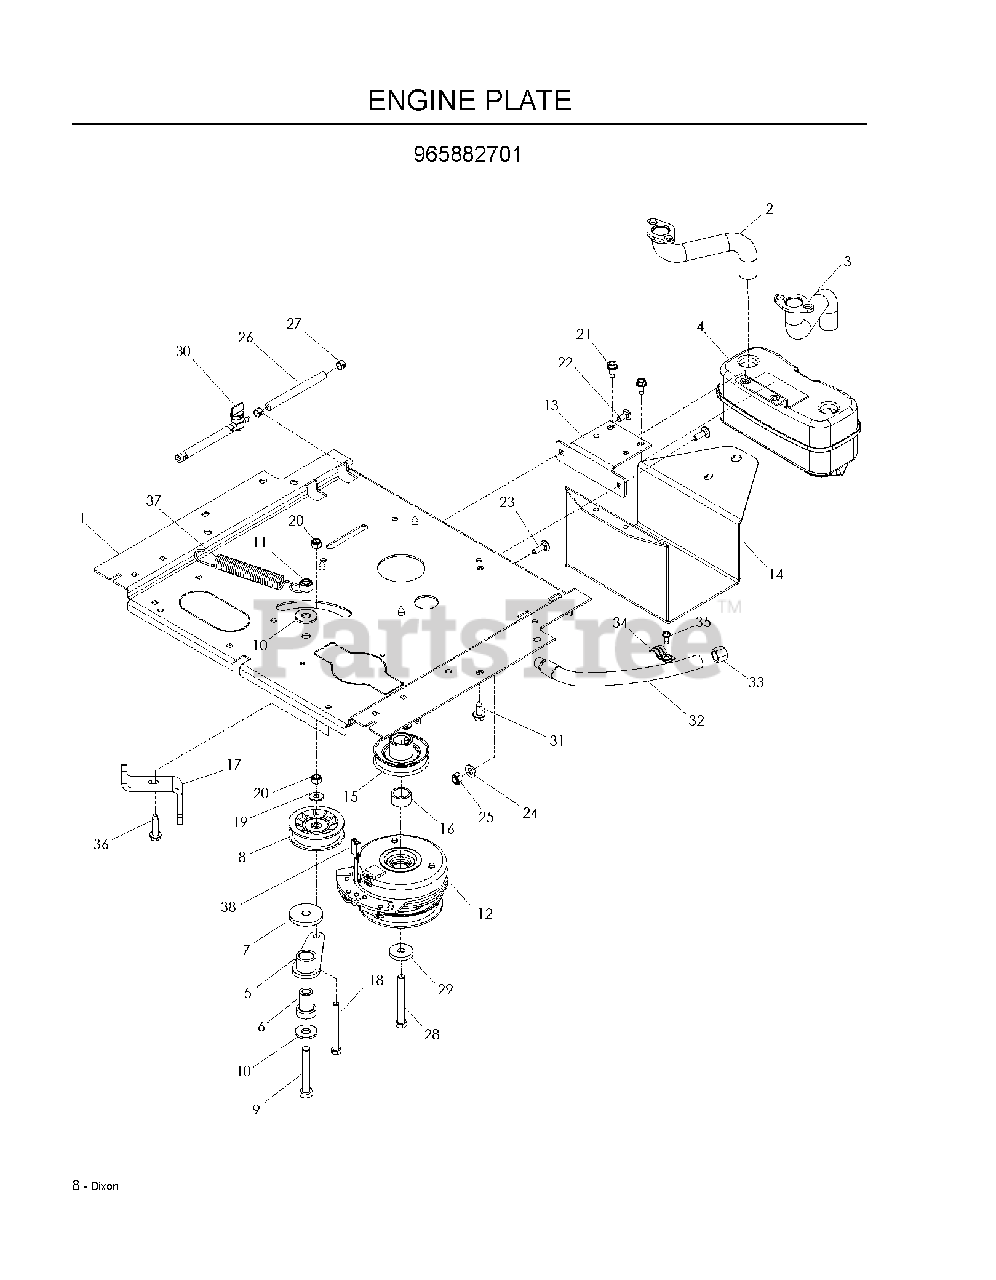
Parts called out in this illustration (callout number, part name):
1	PLATE, ENGINE, BLACK
2	RP.EXHAUST.TUBE.LH.BS/TWIN
3	RP.EXHAUST.TUBE.RH.BS/TWIN
4	MUFFLER ASM TWIN
5	IDLER SPINDLE
6	HEAVY WASHER
7	IDLER ARM WELDMENT
8	PULLEY, IDLER
9	HCS 1/2C X 3 1/4
10	WASH USS FLAT 1/2
11	NUT 1/2-13 HEX NYLOC ZD
12	CLUTCH, 105 FT-LBS
13	BRACKET, MUFFLER, BLACK
14	GUARD, MUFFLER, BLACK
15	PULLEY, ENGINE
16	T & B SPACER
17	STOP, CLUTCH BLK
18	HCS 3/8-16X3 1/2 GR5
19	WASHER 5/16 FLAT
20	NUT 3/8-16 NYLOC
21	BOLT 5/16-18 X 3/4
22	BOLT 5/16C X 3/4" CARRIAGE
23	RHSNB 5/16C X 1
24	FLAT WASHER 5/16 SAE
25	NUT 5/16 NYLOC
26	FUEL LINE 5"
27	HOSE CLAMP
28	HCS 7/16-20X3-1/2 GR 5 ZN
29	CLUTCH, WASHER
30	FUEL VALVE
31	HHFS 3/8-16 X 1.0 THD FORMING
32	OIL DRAIN HOSE
33	DRAIN CAP
35	SCREW 1/4 X 5/8
36	BOLT 3/8-16 X 1 1/2 ZINC CLEAR
37	SPRING, DECK DRIVE
38	CLUTCH HARNESS
